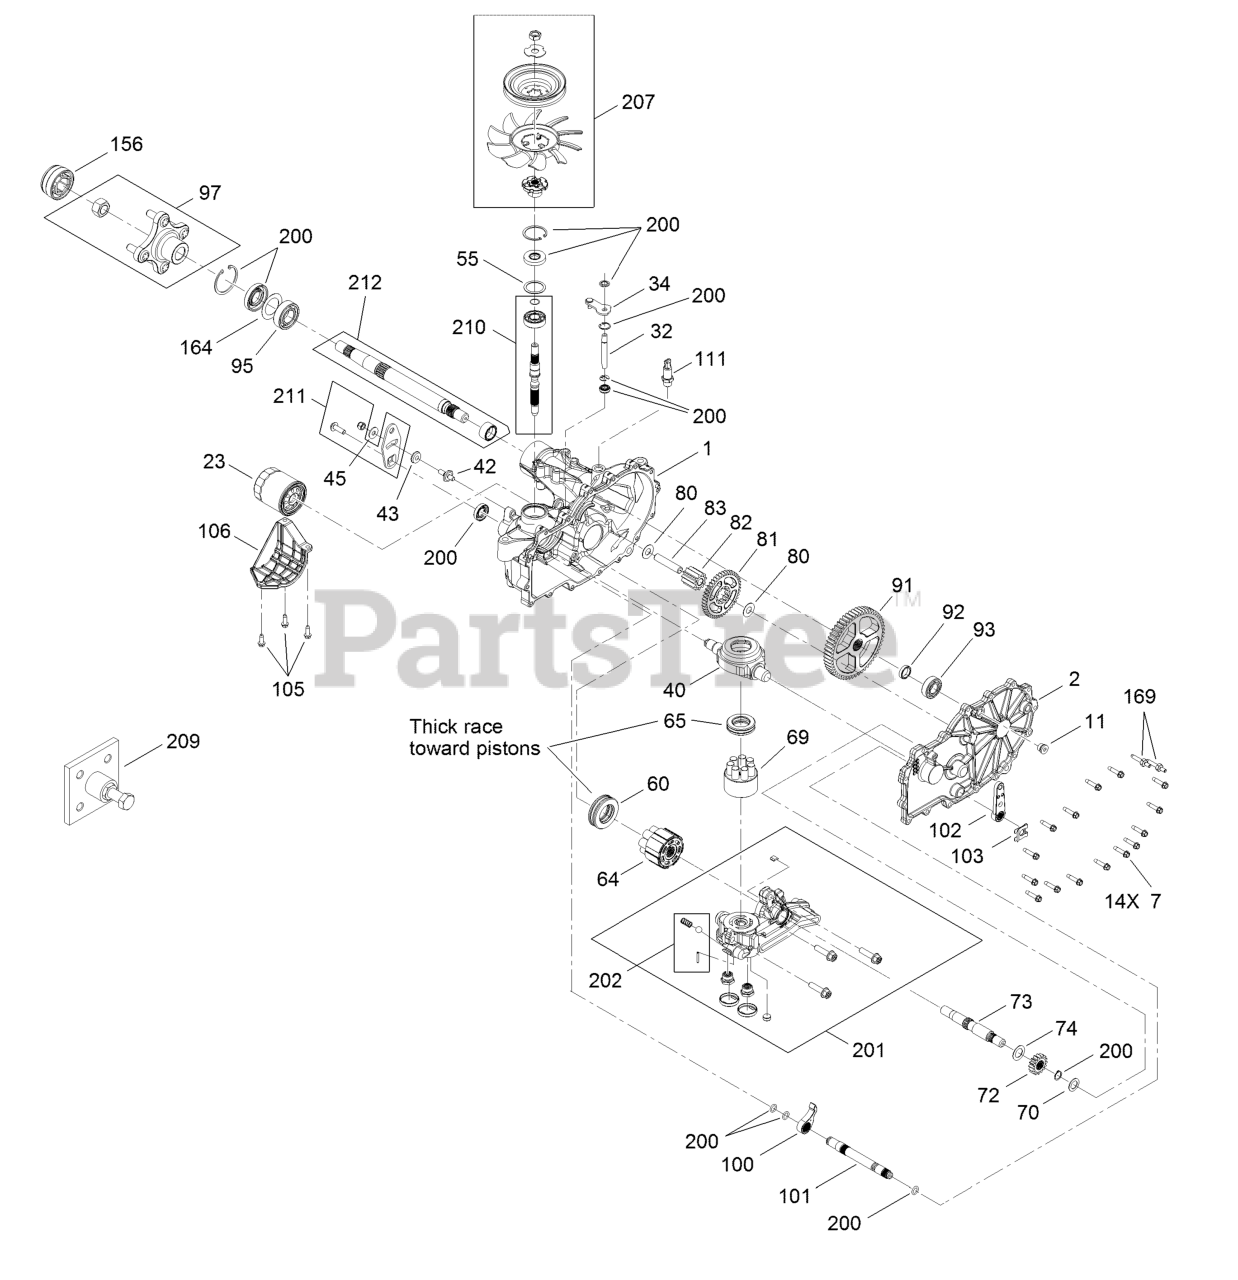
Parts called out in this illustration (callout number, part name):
1	MAIN HOUSING KIT
2	RH HOUSING SIDE KIT
7	SCREW-HHF
11	PLUG-THREAD, STRAIGHT
23	ELEMENT-OIL FILTER, HYD
32	ROD-BYPASS
40	SWASHPLATE-TRUNNION
43	PUCK-FRICTION
60	BEARING-THRUST
64	MOTOR CYLINDER BLOCK KIT
65	BEARING-THRUST
69	PUMP BLOCK ASM
70	WASHER-FLAT
72	GEAR-16T
73	SHAFT-MOTOR
81	GEAR-43T
82	GEAR-11T
83	PIN-JACKSHAFT
91	GEAR-54T
93	BEARING-BALL
95	BEARING-BALL
97	HUB KIT
100	PAWL-BRAKE
101	SHAFT-BRAKE, INBOARD
102	HANDLE-BRAKE
103	CLIP-RETAINING
106	GUARD-FILTER, RH
111	ADAPTER-STRAIGHT
156	COVER-NUT, AXLE
200	SEAL KIT
201	RH CENTER SECTION KIT
202	CHARGE RELIEF KIT
207	FAN PULLEY KIT
210	INPUT SHAFT KIT
211	CONTROL ARM KIT
212	AXLE SHAFT KIT
